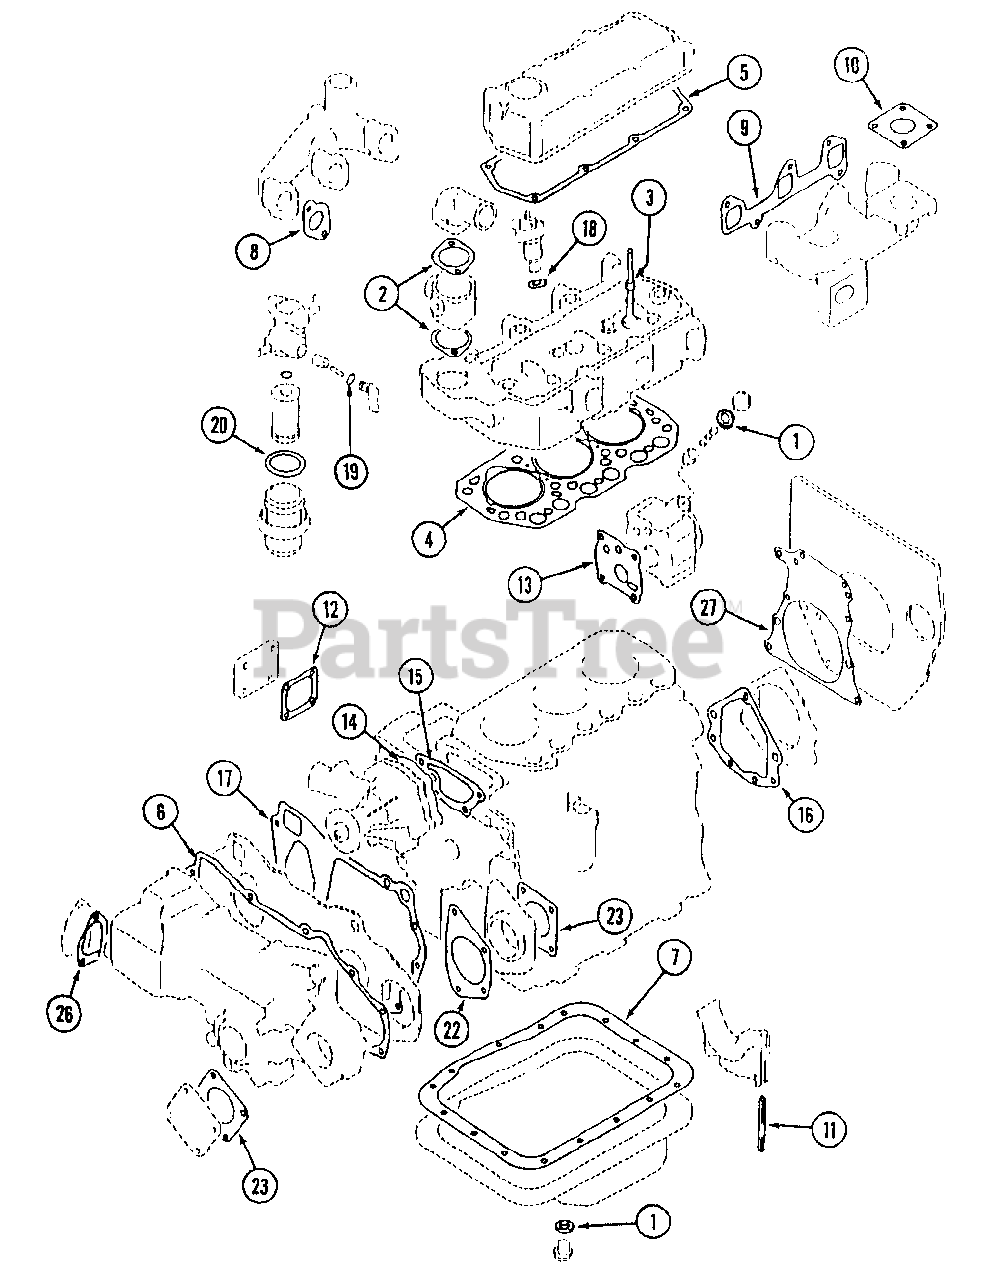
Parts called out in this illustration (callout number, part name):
1	Gasket Kit
1	Gasket, Oil Drain Plug
2	Gasket
3	Seal, Valve Stem
4	Gasket, Cylinder Head
5	Gasket, Rocker Cover
6	Gasket, Gear Case
7	Gasket, Oil Pan
8	Gasket, Inlet
9	Gasket, Exhaust Manifold
10	Gasket
12	Gasket, Cover
13	Gasket, Oil Pump Body
14	Gasket, Water Pump
15	Gasket, Water Pump
16	Gasket, Oil Seal
17	Gasket, Front Plate
18	Gasket, Nozzle Holder
19	O-Ring, Valve
20	O-Ring, Filter Cup
22	Gasket, Housing
23	Gasket, Oil Pump Cover
26	Gasket, Governor Cover
27	Gasket, Rear Plate
